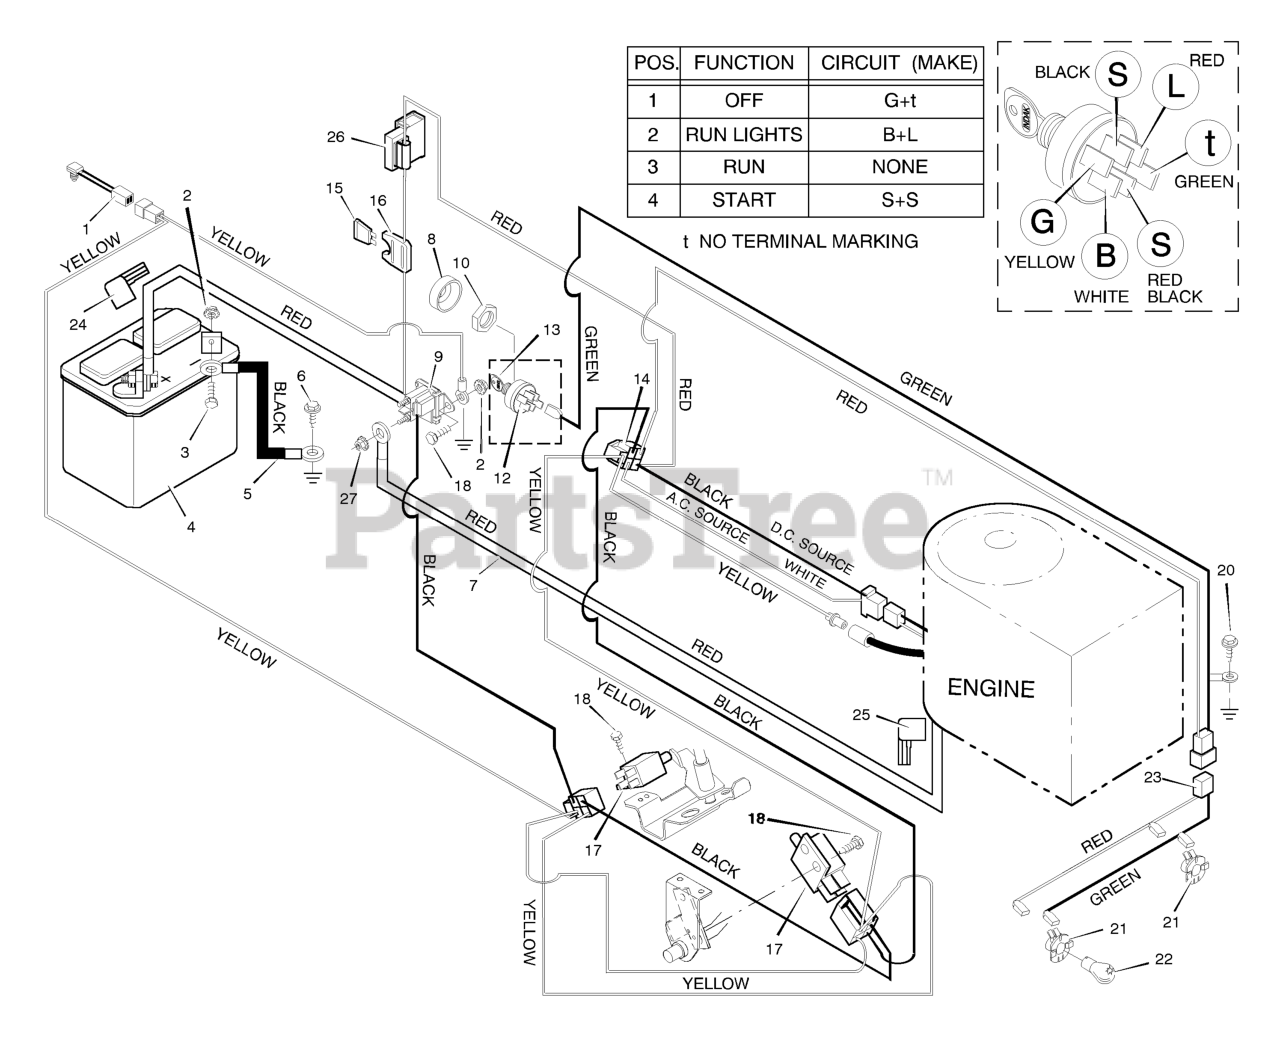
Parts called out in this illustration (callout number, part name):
1	Switch, Seat Sensor
2	Locknut
3	Bolt, Hex
4	Battery
5	Cable, Battery Ground
7	Cable, Red Battery
8	Cap, Ignition
9	Solenoid
10	Nut
12	Switch, Ignition
13	Key, Ignition
14	Harness, Chassis Wire
16	Holder, Fuse
17	Switch, Clutch
20	Screw
21	Socket, Light
22	Bulb, Light
23	Harness, Light Wire
24	Cover, Terminal
25	Cover,
26	Ammeter
27	Locknut
